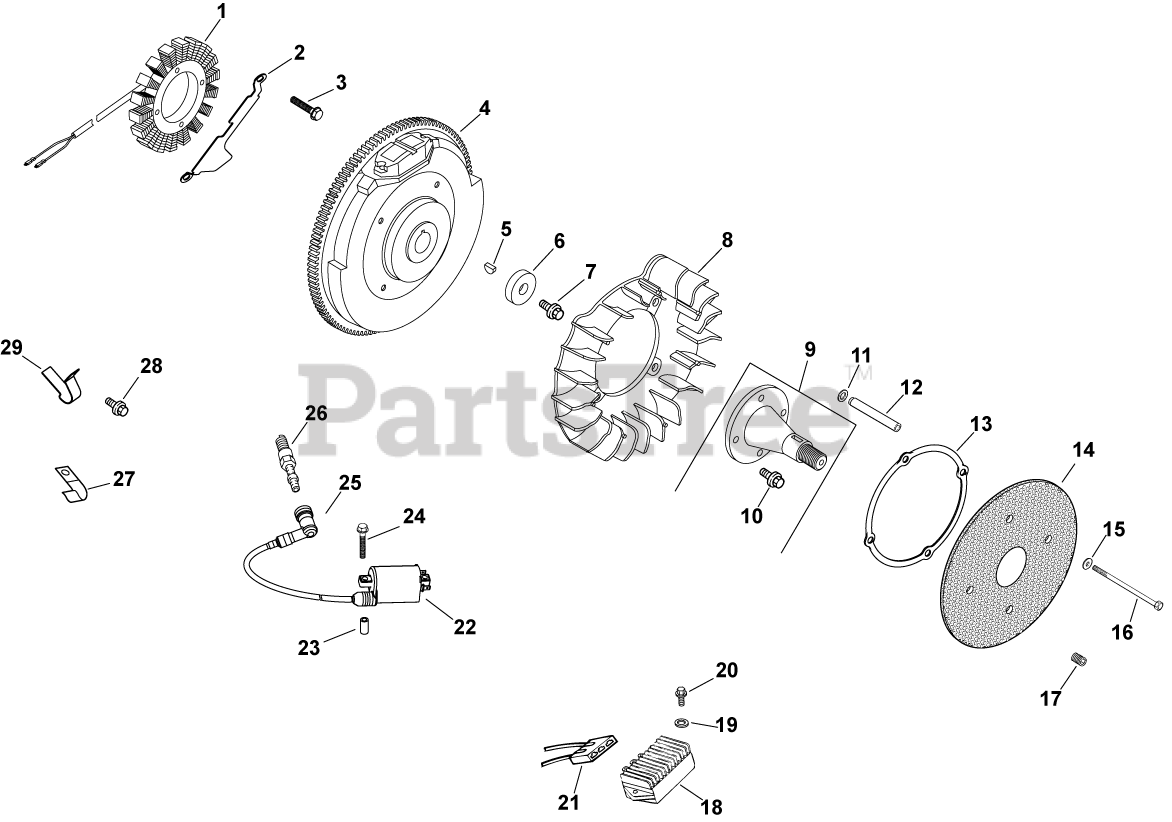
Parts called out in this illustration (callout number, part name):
1	KIT, 25 AMP STATOR ASSY.
2	BRACKET, STATOR WIRE
3	SCREW, THD FROM M5X0.8X30
4	FLYWHEEL, PAINTED-USE 24 025 23-S
5	KEY, 3/16" X 5/8"
6	WASHER, FLAT 13/32"
7	SCREW, FLG M10X1.5X45 - (#25086361S)
9	KIT, FRONT DRIVE SHAFT
10	SCREW, FLG M8X1.25X25
11	WASHER, SPRING 10 MM
13	RING, SUPPORT USE 25 141 08-S
14	SCREEN, GRASS
15	WASHER, FLAT 1/4" (O.D. 5/8")
16	SCREW, CAP M6X1.0X99.5
17	SCREW, SKT SET #10-24X1/4"
18	REG-RECTIFIER (25 AMP)-USE 25 403 21-S
19	WASHER, FLAT 3/16"
20	SCREW, PHL HD #11-16X7/8"
21	CONNECTOR, BODY (KM)-USE 25 155 41-S
22	COIL, IGNITION
24	SCREW,WSH HD TAP 1/4-14X1 1/2"
25	BOOT, SPARK PLUG
26	PLUG, SPARK (PRO SERIES)
28	SCREW,FLG THD FRM M5X0.8X16-(#25086398S)
29	CLAMP, INSULATED
